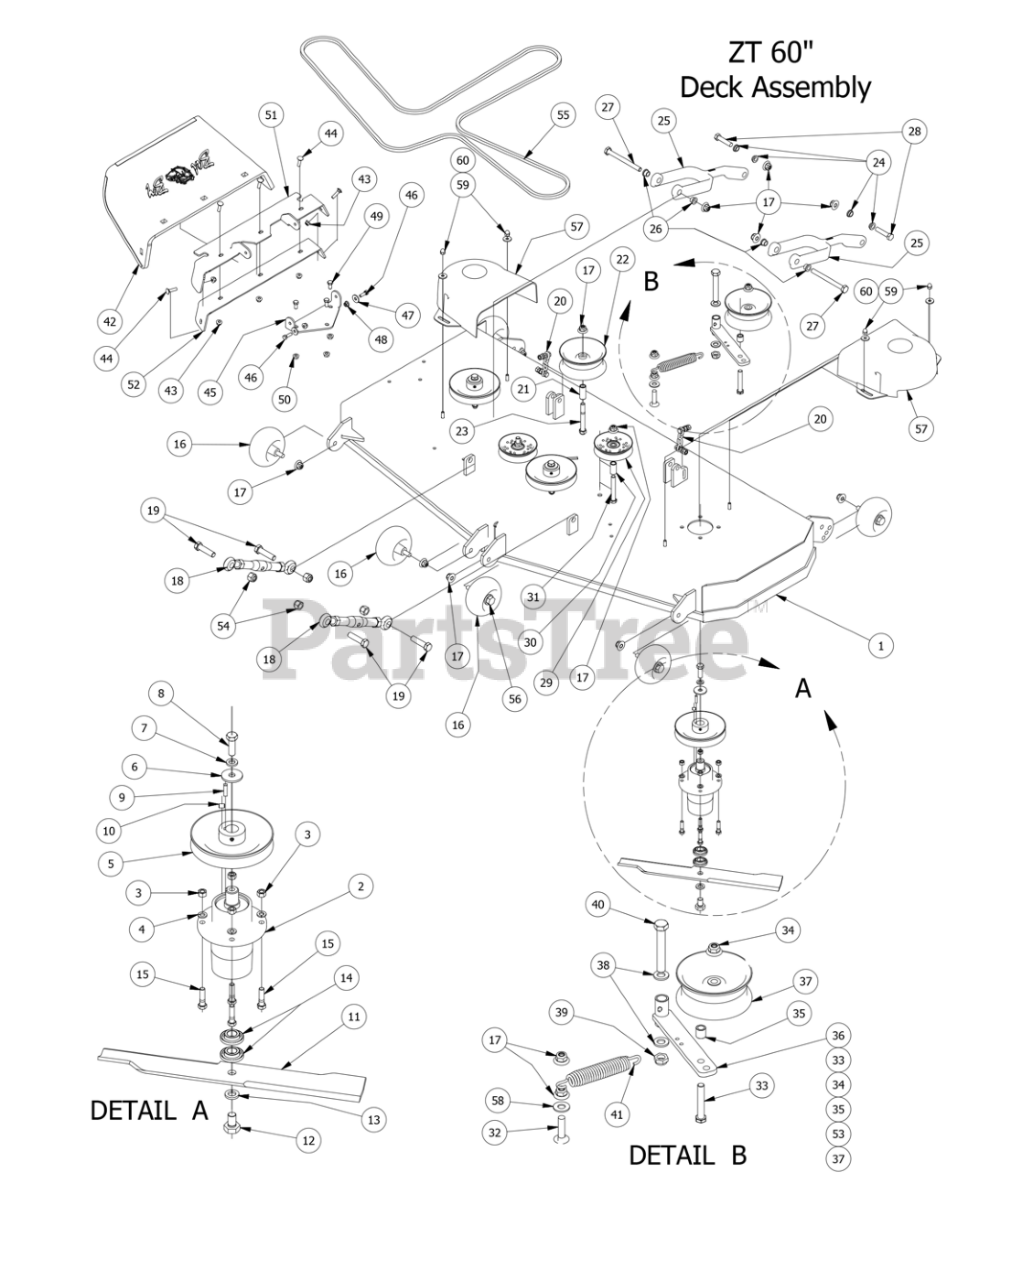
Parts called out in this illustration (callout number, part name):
1	2014 60" ZT/ CZT Deck
2	Spindle- Aluminum
3	3/8" Hex Nut
4	3/8" Lock Washer
5	6 1/4" Drive Pulley
6	1/2 Belleville Washer
7	1/2" Lock Washer
8	1/2"-20 x 1 1/2 Grade 5 Fine Thread Bolt
9	1/4" x 1" Key
10	5/16 Set Screw
11	60 Inch Fusion Blade
12	5/8" x 1 1/2" Grade 8 Bolt
13	5/8" Lock Washer
14	Spindle Bearing
15	3/8-16 X 1-1/4 GR 5 Hex Bolt
16	Deck Wheel
17	1/2-13 Nylon Flange Nut-Orange
18	Turnbuckle (Top Link)
19	5/8" x 2 1/2" Hex Bolt
20	Chain assembly
21	1 3/4" Pulley Spacer
22	5 3/4" Deck Idler Pulley
23	1/2" x 4" Bolt (Grade 8)
24	Flange for Lower Deck Arm
25	Deck Arm Assembly
26	Flange Bushing For Deck Arm upper
27	1/2" x 5 1/2" Bolt
28	1/2-13X 2-1/4 GR Hex Bolts
29	4-3/4 Idler Pulley
30	.502 ID X.75 OD X 1.500 Leng
31	1/2 x 3 1/2 Flange Bolt Grade 8
32	1/2 x 2" Carriage Bolt
33	1/2-13 x GR 5 Hex Bolt Zinc
34	1/2-13 Nylon Flange Nut-Orange
35	3/4 OD x 1/2 ID x 3\4 Length
36	Deck Idler
37	5 3/4" Deck Idler Pulley
38	.635 ID Plastic Washer
39	5/8-11 Nylon Insert Jam Half Nut
40	5/8" x 4" Hex Bolt
41	2009 Deck/Pump Idler Spring
42	Rubber Discharge Chute
43	5/16" Nylon Flange Nut
44	5/16" x 1 1/4" Carriage Bolt
45	Discharge Chute Hanger (deck mounted)
46	5/16" x 1" Bolt
47	.360 ID Plastic Washer
48	5/16" Nylon Flange Nut
49	3/8" x 3/4" Hex Bolt
50	3/8" Flange Nut
51	60" Discharge Chute Upper Hanger
52	60" Lower Hanger
53	Deck Idler Assembly (Components 33,34,35,36,37)
54	5/8 Std NC Nylock Nut
55	60" ZT Deck Belt
56	Deck Wheel Bolt
57	2014 ZT Pulley Cover
58	1/2" Washer (Grade 8)
59	Acorn nut-pulley Cover
60	.360 ID Plastic Washer-Black
